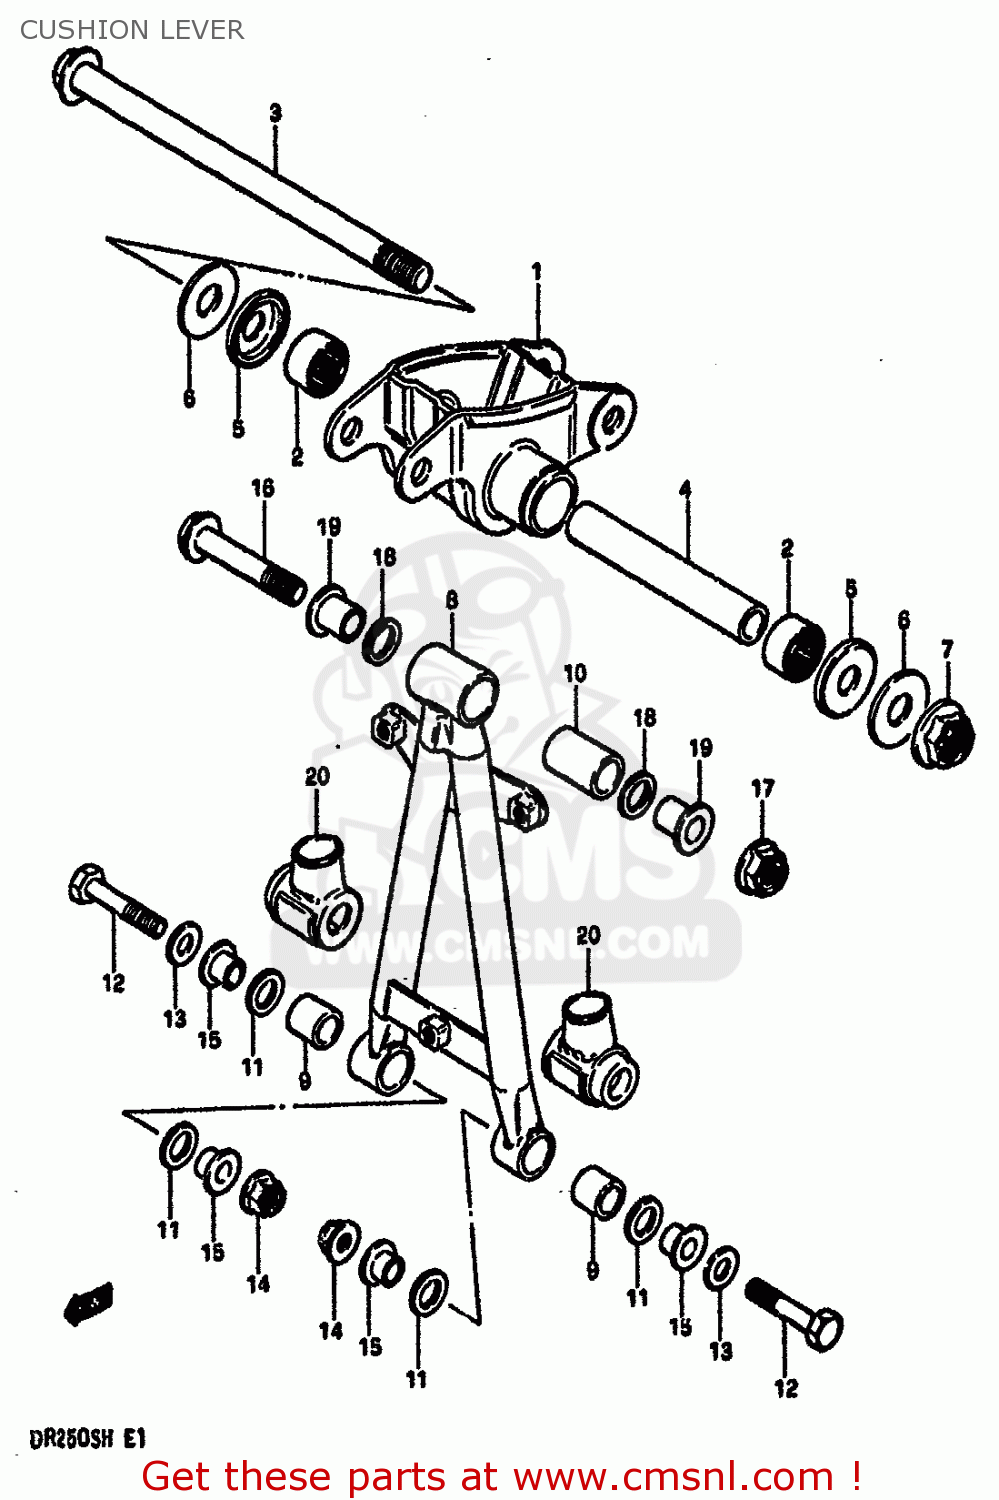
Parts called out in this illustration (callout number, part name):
1	LEVER ASSEMBLY,REAR CUSHION
2	BEARING(17X25X20)
3	SHAFT,REAR CUSHION LEVER
4	SPACER
5	DUST SEAL,RR CUSHION LEVER
6	WASHER
7	NUT 12MM
8	ROD SET,REAR CUSHION LEVER
9	BUSHING
10	BUSH,UPPER
11	DUST SEAL,RR CUSHION LOD LWR
12	BOLT,REAR CUSHION ROD
13	WASHER
14	NUT
15	SPACER,RR CUSHION ROD LWR
16	BOLT(10X65)
17	NUT
18	DUST SEAL,LEVER CUSHION UNIT
19	SPACER,RR CUSHION ROD UPR
20	BOOT,REAR CUSHION ROD,LOWER
